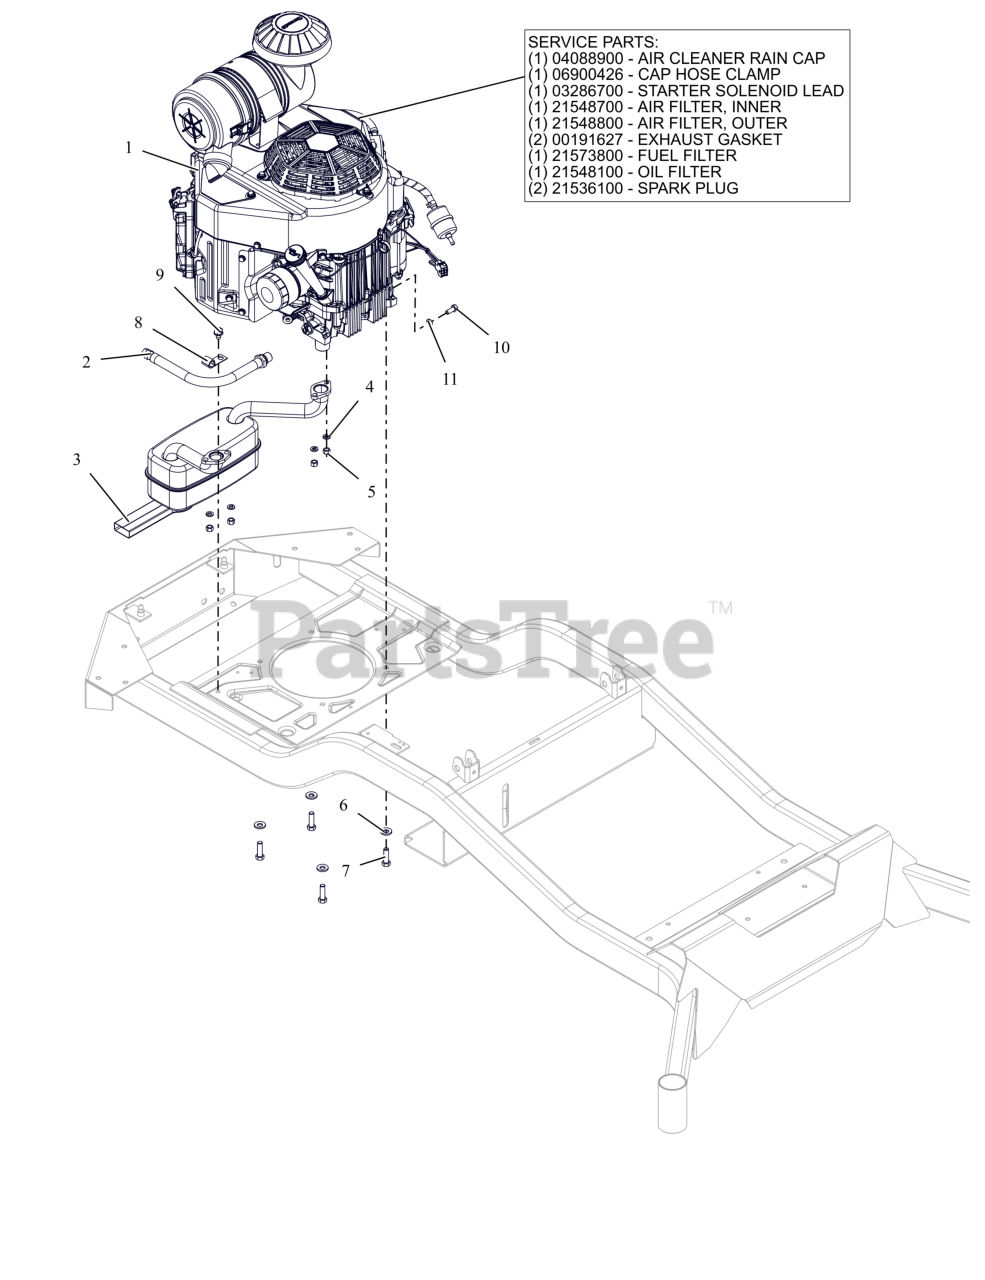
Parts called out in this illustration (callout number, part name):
1	ENGINE, KAWASAKI FX730
1	CAP, KAW 11065-7025
1	CLAMP, HOSE #36 SS 1.813-2.75
1	LEAD - STARTER SOLENOID
1	FILTER, INNER - KAW
1	FILTER, OUTER
1	GASKET, MUFFLER S/O
1	FUEL FILTER-KAWASAKI FR
1	OIL FILTER, KAWASAKI FR
1	PLUG, SPARK
2	HOSE, OIL DRAIN
3	MUFFLER, KAWASAKI
4	WSHR,LK-REG .312X.078 ZCC
5	NUT-LK-TOP-FLG M8 ZCC
6	WASHER, 3/8" SPRING DISC
7	BLT, HEX .38-16X1.25 G5 ZCC NT
8	J-CLAMP
9	SCR,TAP .375-16X.50 HWH TR ZCC
10	BLT, HEX M8-1.25X20 G8.8 ZCC
11	WSHR,LK-REG .312X.078 ZCC
